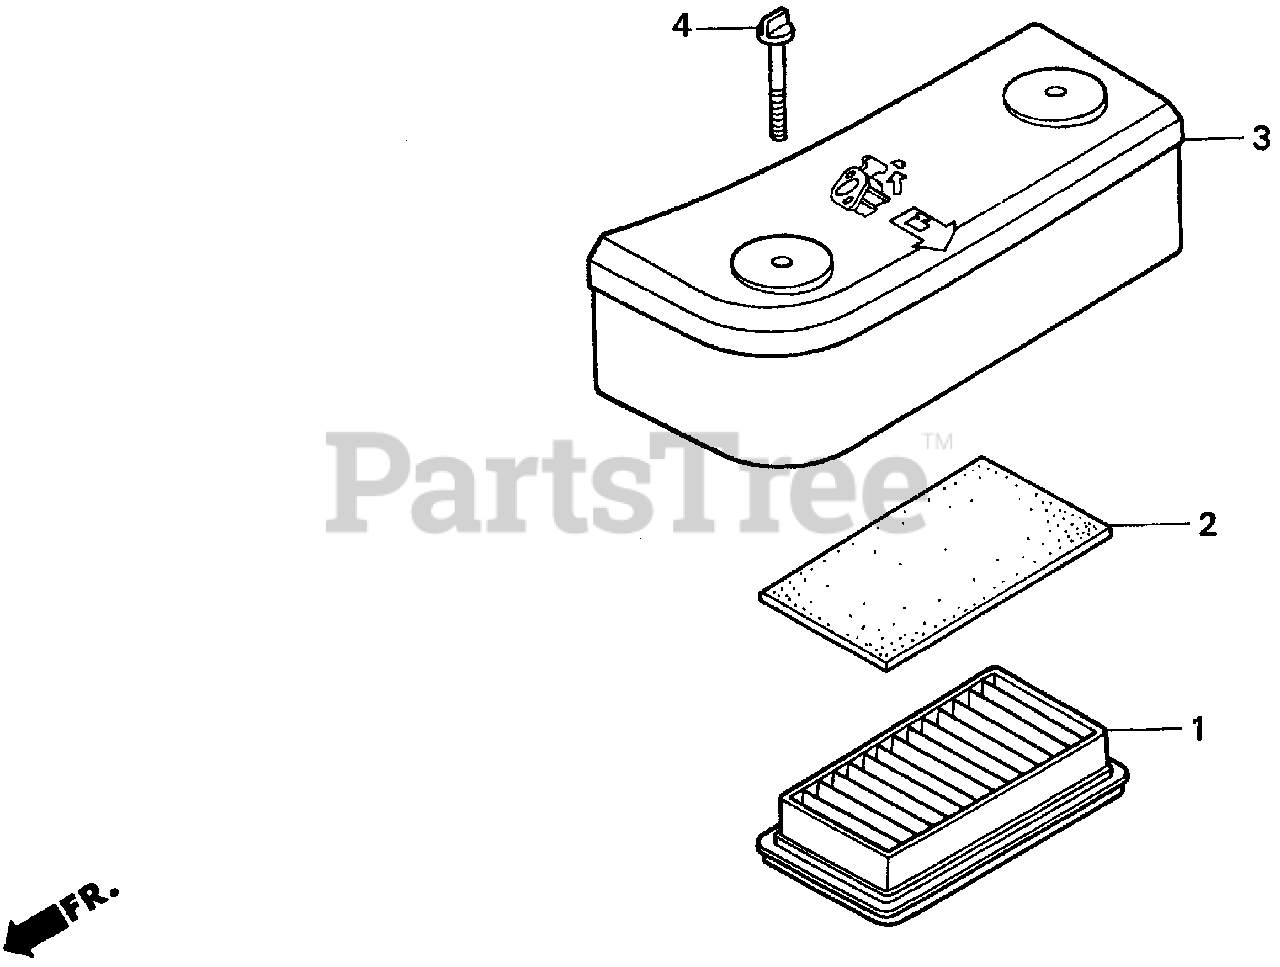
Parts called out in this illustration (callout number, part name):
1	ELEMENT, AIR CLEANER
2	FILTER (OUTER)
3	COVER, AIR CLEANER *R8* (TEXTURED) (BRIGHT RED)
4	BOLT, AIR CLEANER (6MM)
